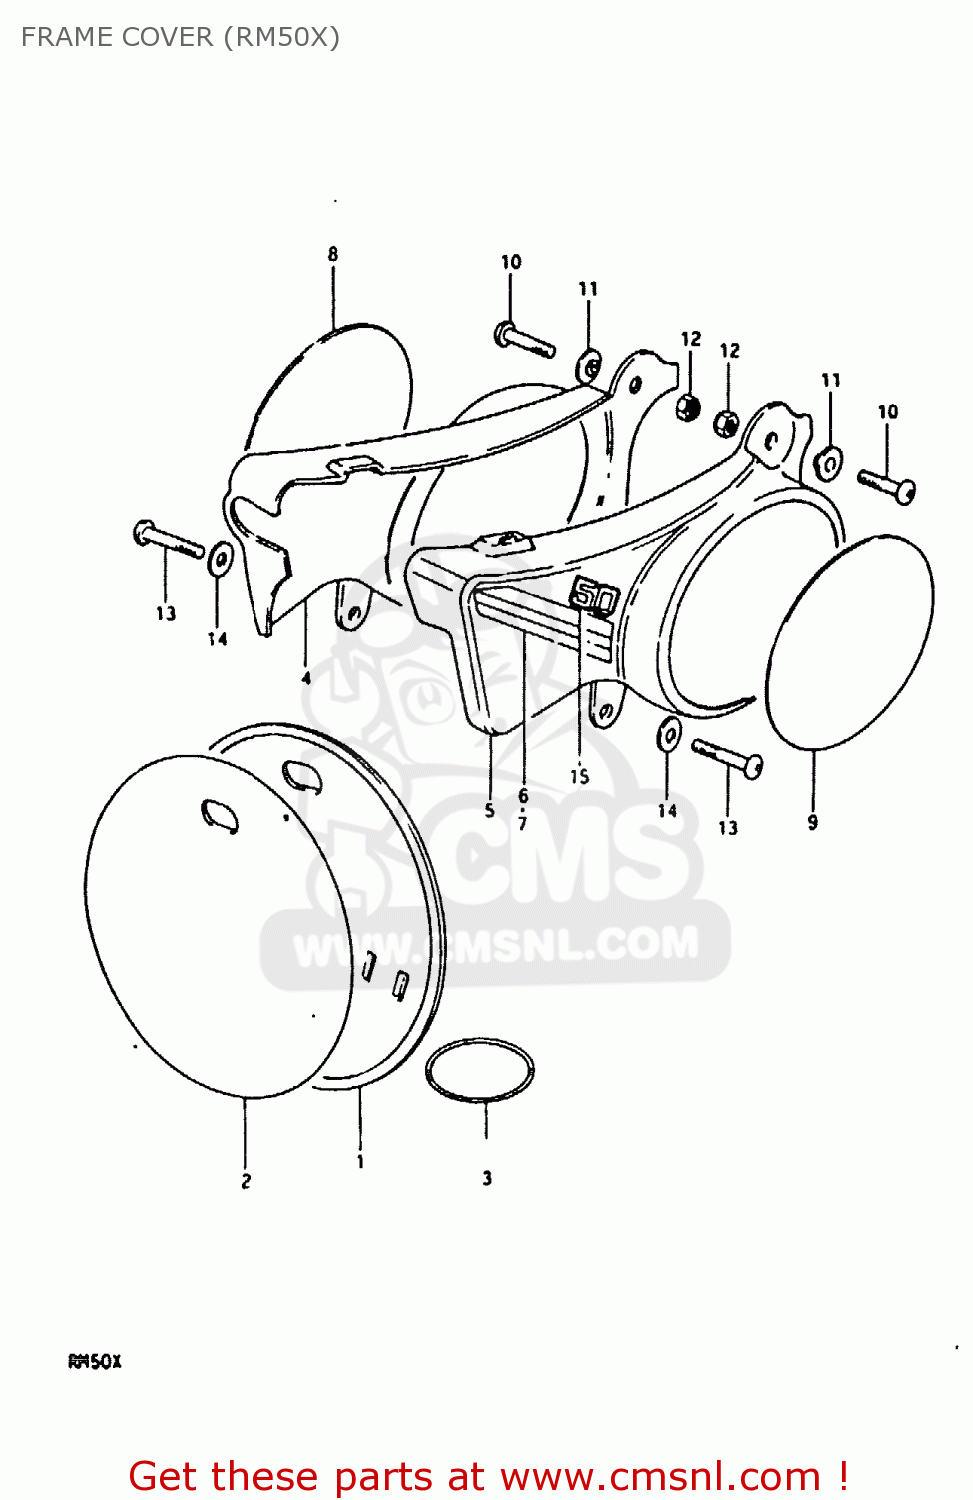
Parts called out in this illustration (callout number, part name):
1	PLATE,NUMBER,FRONT
2	EMBLEM,FRONT NUMBER PLATE
3	O-RING
4	COVER,FRAME,RIGHT
5	COVER,FRAME,LEFT
6	TAPE, STRIPING RH
7	TAPE, STRIPING LH
8	TAPE,FRAME COVER NUMBER PLATE
9	LABEL,FRAME COVER
10	SCREW
11	WASHER
12	NUT
13	SCREW
14	WASHER
15	EMBLEM
